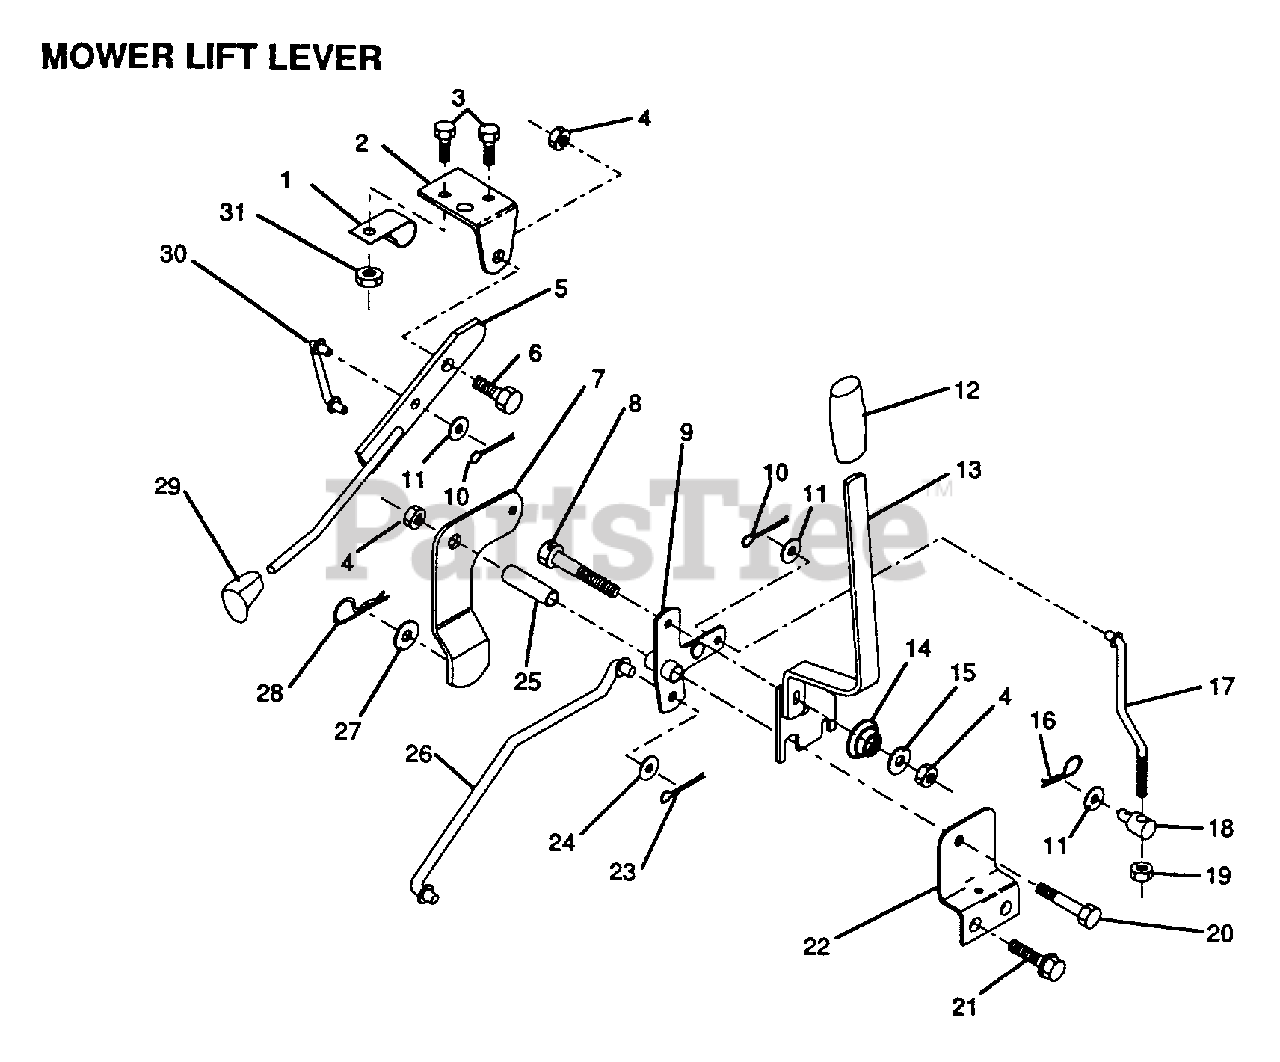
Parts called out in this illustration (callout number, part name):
1	CLIP T
2	BRKT CLUTCH
3	BOLT
5	CLUTCH LEVER AS
6	"BOLT, SHOULDER LT"
7	CLUTCH ARM ASS'Y
8	BOLT
9	"BELLCRANK,LIFT"
11	WASHER
12	GRIP HANDLE
13	LIFT HANDLE ASS'Y
14	SPRING COMPRESSIO
15	WASHER T
16	COTTER PIN
17	LINK FRT LIFT
19	NUT
20	BOLT
21	SCREW LT
22	"BRKT,MOWER HGT"
23	PIN COTTER 1/8
25	TUBE SPACER
26	"ROD,MOWER LIFT "
27	WASHER
29	KNOB
30	"LINK,MOWER LIFT"
